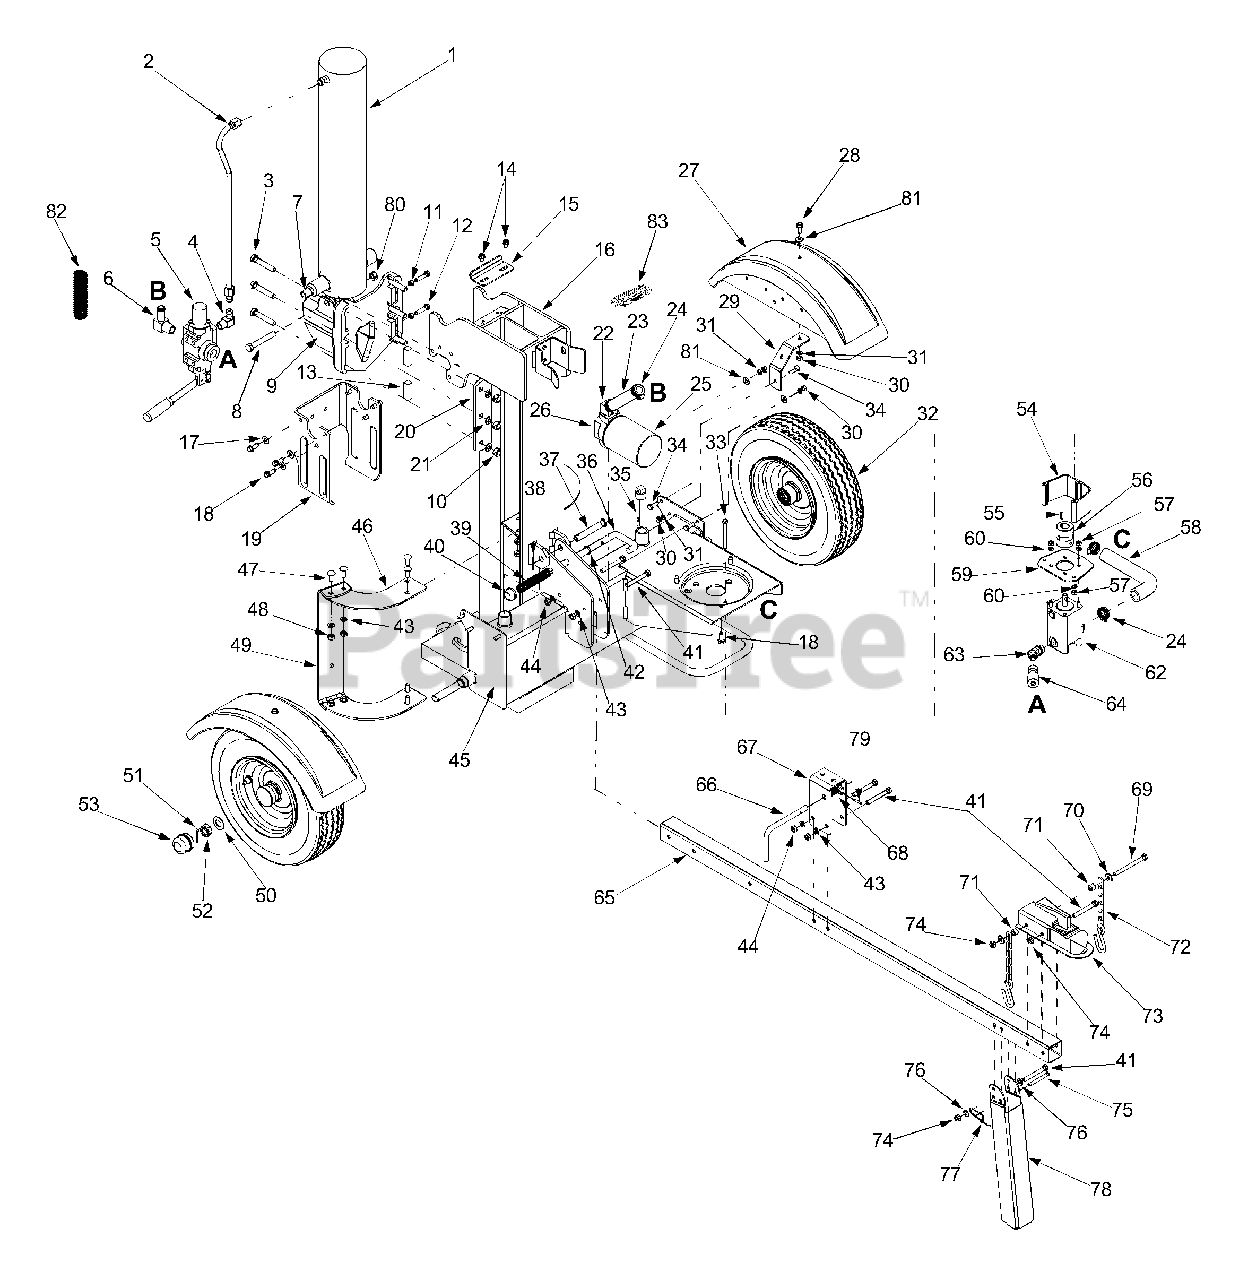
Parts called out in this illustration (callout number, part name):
1	Hydraulic Cylinder
1	Seal Kit 4.5" for Fisher Cylinder 718-0769
1	Kit Seal 4.5" for XINGHUI cylinder 718-0769A
1	Kit Seal 4.5" for ENERGY cylinder 718-0769A
2	Hydraulic Tube
3	Hex Cap Screw 1/2-20 x 2.75
4	90 Degree Solid Adapter
6	Return Elbow
7	Nipple Pipe 1/2-14
8	Hex Cap Screw 1/2-13 x 3.25
9	Wedge Assembly
10	Lock Nut 1/2-20
11	Hex Jam Nut 3/8-24
12	Hex Cap Screw 3/8-24 x 1.5
14	Hex Washer Screw 5/16-18 x.75
17	Flat Washer.406 ID x.875 OD
18	Hex Washer Screw 3/8-16 x 1.0
21	Lock Washer 1/2
22	Adapter 3/4-14
23	Return Hose 3/4" ID x 44" Lg.
24	Hose Clamp 5/8"
25	Oil Filter
26	Filter Housing
27	Black Fender
28	Hex Washer Screw 5/16-18 x.875
30	Hex Nut 5/16-18
31	Lock Washer 5/16
32	Wheel Assembly
33	Hex Screw 5/16-24 x 3.25
34	Hex Cap Screw 5/16-18 x.875
35	Vented Dipstick
36	Lock Rod
37	Clevis Pin
38	Cotter Pin
39	Compression Spring
40	Push Cap
41	Hex Bolt 3/8-16 x 3"
42	Flat Washer.635 ID x.93 OD
43	L-Washer 3/8"
44	Hex Nut 3/8-16
45	Frame Assembly
48	Lock Nut 3/8-16
50	Flat Washer.760 ID x.500 OD
51	Cotter Pin
52	Slotted Nut 3/4-16
53	Hub Cap
54	Coupling Shield
55	Square Key 3/16" x.75
56	Flexible Coupling
57	Hex Nut 5/16-24
60	Lock Washer 5/16" ID
62	Gear Pump (11gpm)
63	45 Degree Elbow
64	High Pressure Hydraulic Hose
66	Latch Rod
68	Compression Spring
69	Hex Cap Screw 3/8-16 x 4.25
70	Flat Washer.385 ID x.870 OD
71	Spacer.375 ID x.625 OD
72	Chain
73	Coupling Hitch
74	Hex Lock Nut 3/8-16
75	Clevis Pin
76	Flat Washer.375 ID x.738 OD
77	Spring Pin
80	Hex Lock Nut 1/2-13
81	Flat Washer.343 x.880 x.062
82	Hose Guard
83	Hose Guard
